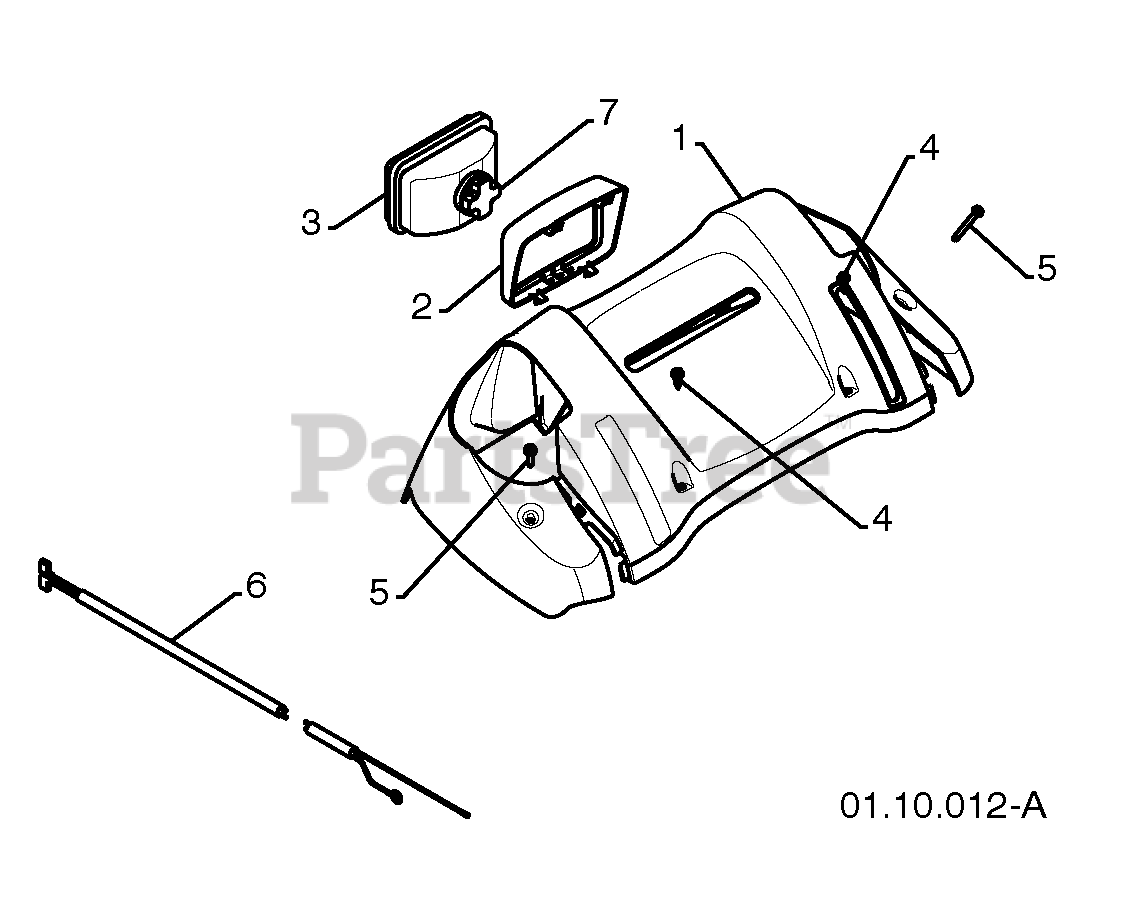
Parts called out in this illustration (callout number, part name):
1	CONSOLE PANEL GRAY
2	HEADLIGHT BEZEL GRAY
3	FLOOD HEADLIGHT
4	SHOULDER SCREW 10-24X0.63
5	SCREW 10-24 X 1.25
6	WIRE HARNESS .704
